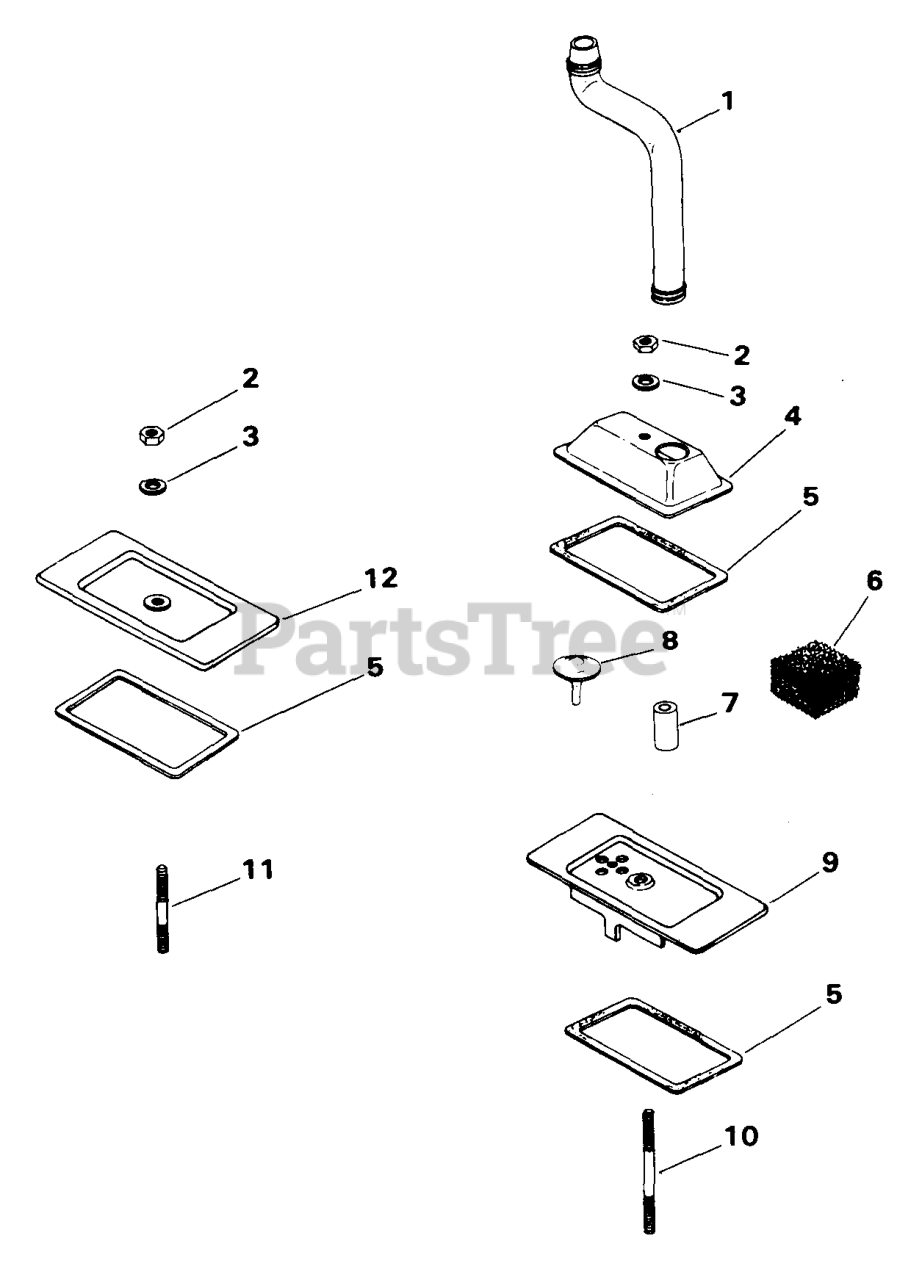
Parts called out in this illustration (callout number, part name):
1	Hose, Breather 3-5/8"
2	Nut, Hex. 1/4-20
3	Washer, Plain 1/4"
4	Cover, #1 Upper Cylinder Valve
5	Gasket, Valve Cover
6	Filter, Breather
7	Seal, Breather
8	Valve, Umbrella
9	Cover, #1 Lower Cylinder Valve
10	Stud, #1 Cylinder Valve Cover - 1/4-20x3-1/4"
11	Stud, #2 Cylinder Valve Cover - 1/4-20x2-1/4"
12	Cover, #2 Cylinder Valve
